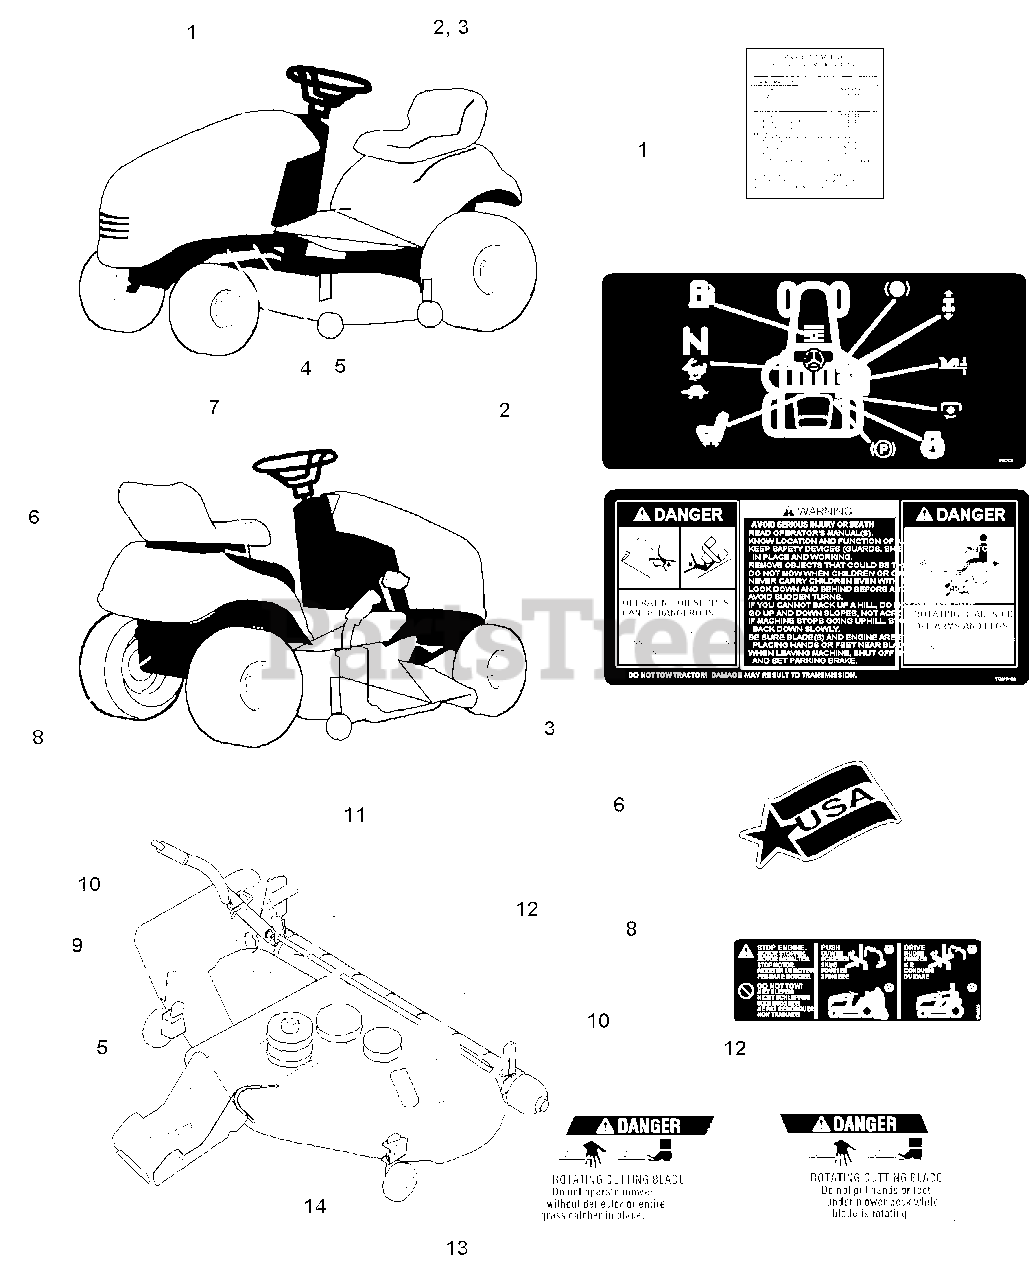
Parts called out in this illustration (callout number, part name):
1	DECAL, Belts & Mower Blades
2	DECAL, Operating Instructions
3	DECAL, Safety Instructions
4	DECAL, Patent (Not Serviced)
5	DECAL, Serial Number (Not Serviced)
5	DECAL, CE & Serial Number Export (Not Serviced)
6	DECAL, USA Logo
7	DECAL, PTO Control Symbols
8	DECAL, Transmission Relese Valve, Hydros only
10	DECAL, Danger Rotating Blades
11	DECAL, Height of Cut
12	DECAL, Danger Rotating Blades
13	DECAL, Free Floating Mower
14	DECAL, OPEI (Not Serviced)
